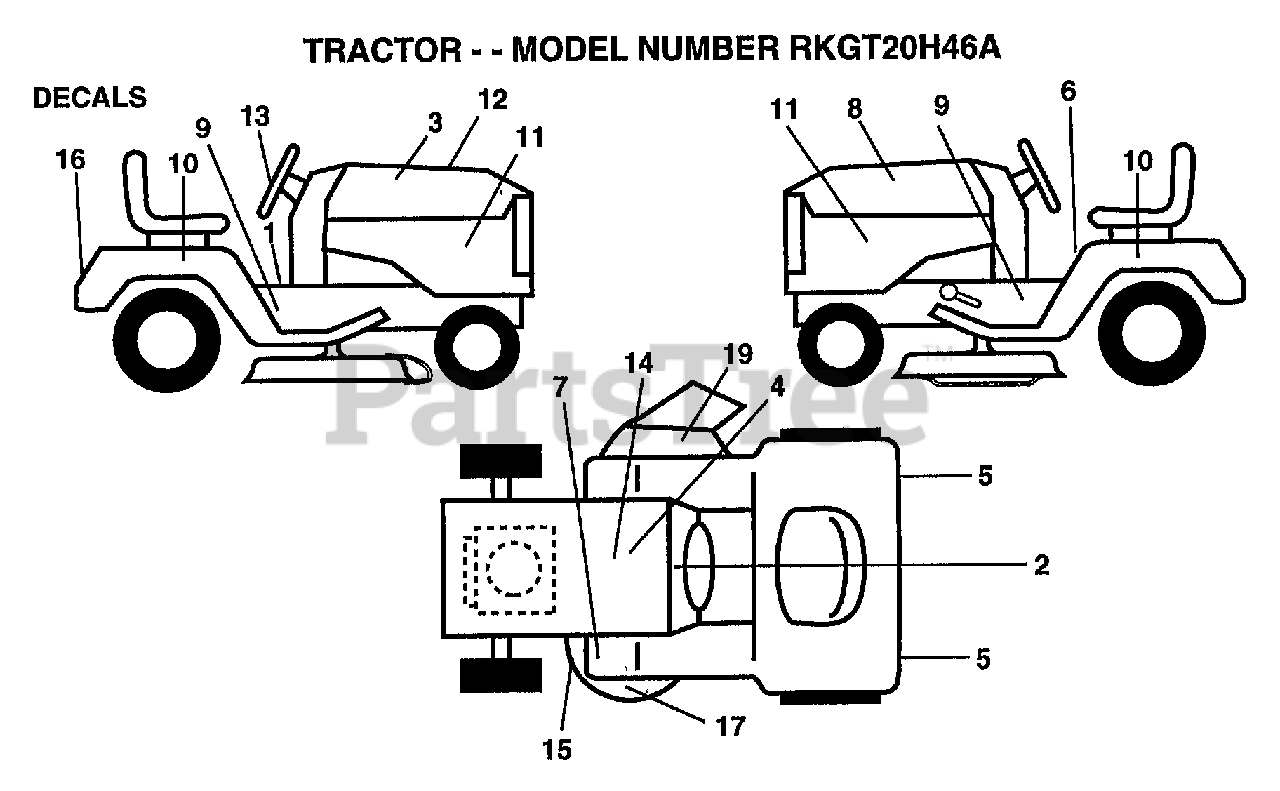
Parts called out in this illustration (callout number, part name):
1	DECAL BRAK PARK
2	DECAL OPER INSTR.
3	DECAL
5	REFLECTOR-TAIL YT
6	DECAL.CAUT.ENG/FR
7	DECAL T
8	DECAL
10	DECAL.FENDER.SIDE
11	DECAL.DASH
12	DECAL
13	DECAL
14	DECAL.BATRY.3-3908
16	DECAL.FENDER.LOGO
17	DECAL.MOWER
19	"DECAL, WARNING"
